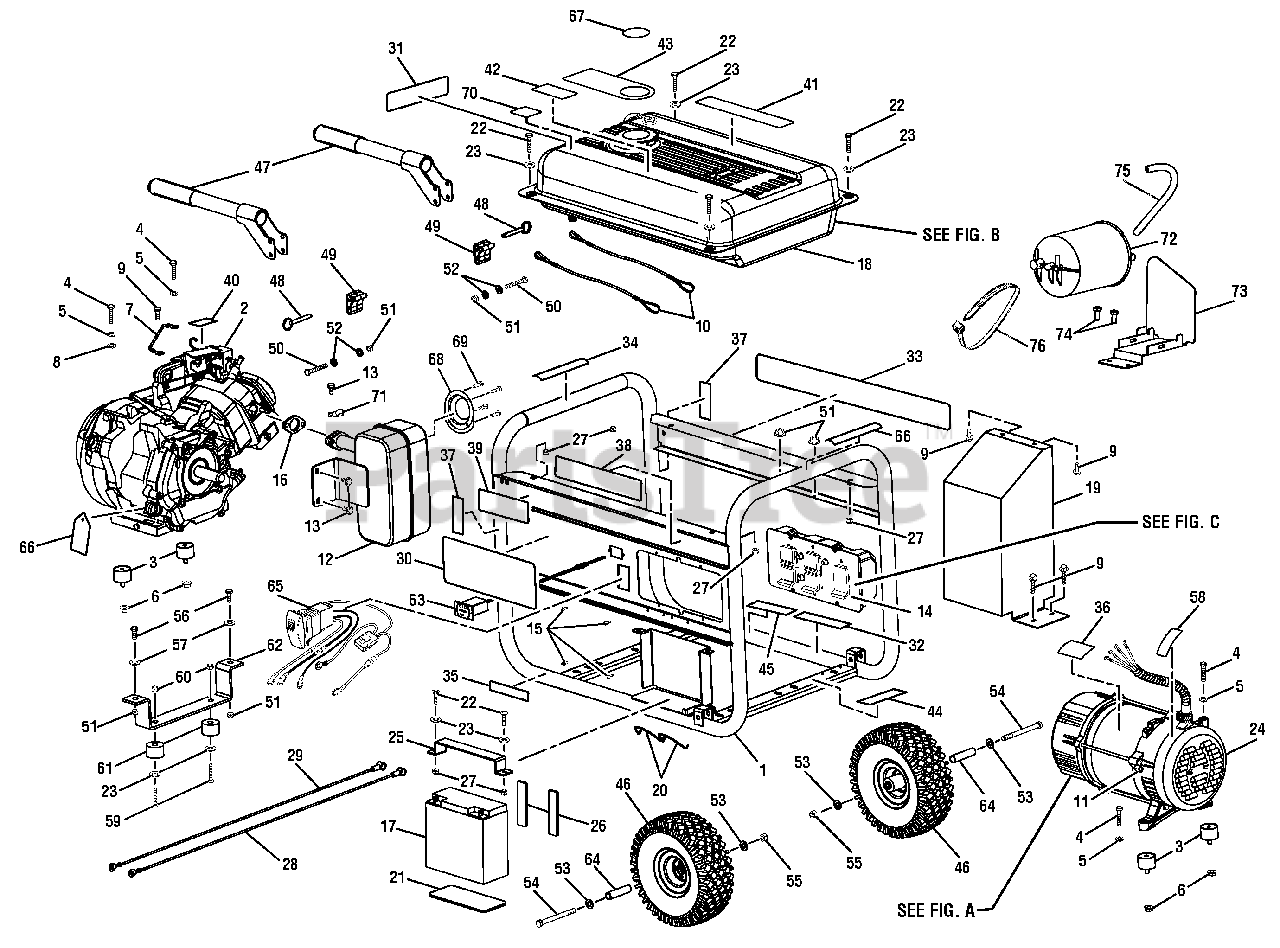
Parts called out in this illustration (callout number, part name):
1	Carrier Assembly
2	Engine (Honda GX390)(Parts available from your local Honda dealer)
3	Isolator
4	Bolt (5/16-18 x 1-1/2 in., Hex Hd.)
5	Lock Washer (5/16 in.)
6	Flange Nut (5/16-18, Hex Hd.)
7	Ground Wire Assembly
8	Star Washer (5/16 in.)
9	Bolt (5/16-18 x 3/4 in., Hex Hd.)
10	Lanyard (3/16 in.)
11	Ground Lug
13	Bolt (5/16-24 x 5/8 in.)
14	Control Panel Assembly
15	Screw (6-20 x 3/8 in.)
16	Muffler Gasket (supplied by Honda)
18	Fuel Tank Assembly
19	Heat Shield
20	Cord Retainer
21	Battery Box Gasket
22	Bolt (1/4-20 x 1 in., Hex Hd.)
23	Washer (1/4 in.)
24	Generator Head w/AVR
25	Battery Hold Down Bracket Assembly
26	Gasket (Battery Hold Down Bracket)
27	Lock Nut (1/4-20)
28	Battery Cable (Red)
29	Battery Cable (Black)
30	Logo Label
31	Starting Instructions Label
32	Hot Surface Label
33	Danger Label
34	Fire Danger Label
35	Engine Lubricant Label
36	Data Plate Label
37	Locking Pin Label
38	Honda Label
39	Electric Start Label
40	Choke Label
41	Quick Start Label
42	CPSC Label
43	Hangtag (Engine Warning)
44	Ground Warning Label
45	Combustion Warning Label
46	Wheel Assembly
47	Handle Assembly
48	Release Pin (5/16 x 2 in.)
49	Handle Bracket Spacer
50	Bolt (5/16-18 x 2-1/4 in., Hex Hd.)
51	Lock Nut (5/16 in.)
52	Washer (5/16 in.)
53	Washer (3/16 in.)
54	Bolt (3/8-16 x 4-1/4 in., Hex Hd.)
55	Nut (3/8-16)
56	Bolt (5/16-18 x 1 in., Hex Hd.)
57	Flat Washer (5/16 in.)
58	Ground Label
59	Bolt (1/4-20 x 1-1/2 in., Hex Hd.)
60	Lock Nut (1/4-20)
61	Rubber Foot
62	Front Foot
63	Hour Meter (120 Volt)
64	Wheel Spacer
65	Engine Switch
66	Fire Distance Label
67	Fuel Stabilizer
68	Spark Arrestor
69	Screw (8-32 x 3/8 in.)
70	E85 Label
72	Canister
74	Bolt (5/16-18 x 3/4 in.)
75	Purge Hose
76	Cable Tie
